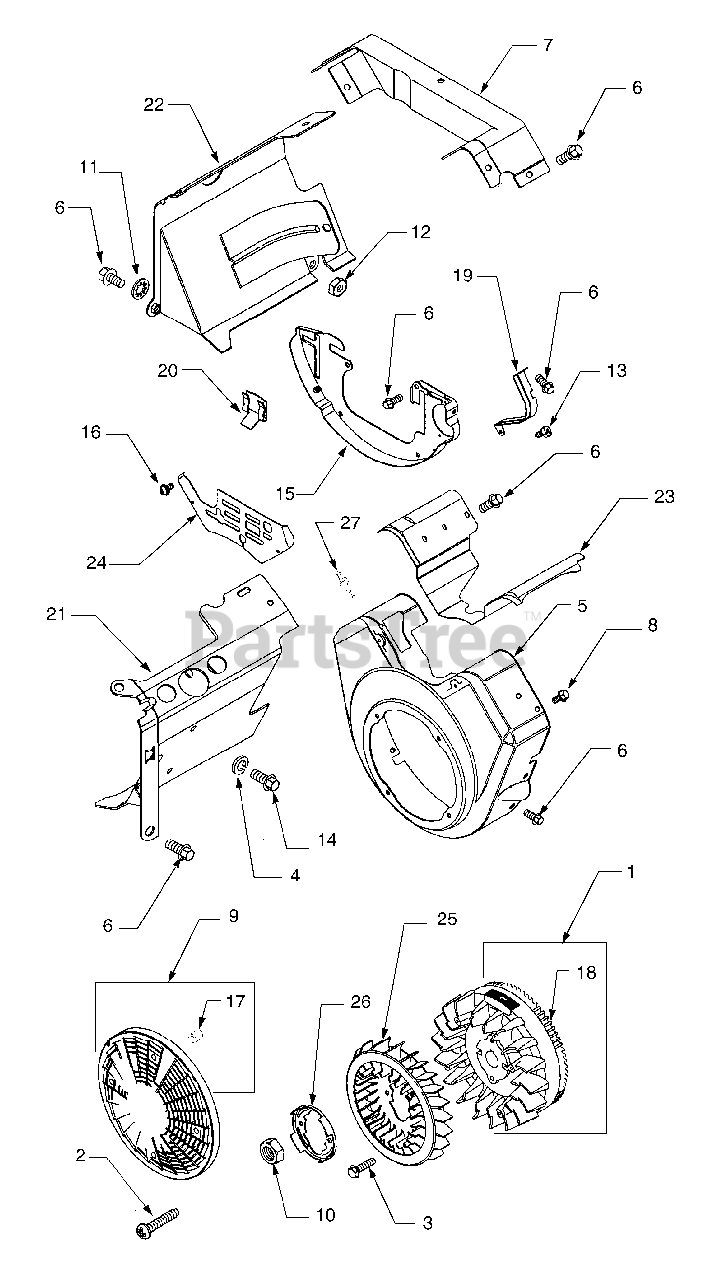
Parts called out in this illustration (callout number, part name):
2	Screw, Phillips
3	Screw, Hex
4	Washer, Lock
5	Housing, Blower
6	Screw, Hex
7	Cover, Air Guide
8	Screw, Hex
9	Screen, Rotating
11	Washer, Lock
12	Nut, Hex
13	Screw, Hex
14	Screw, Hex
15	Plate, Back
16	Screw, Hex
17	Spacer
18	Gear, Ring
19	Guard, Flywheel
20	Clip, Debris
21	Cover, Air Guide (Cylinder #1)
22	Cover, Air Guide (Cylinder #2)
23	Cover, Valley
24	Cover, Carburetor
25	Fan, Flywheel
26	Retainer, Fan
27	Fitting, Hose Barb
